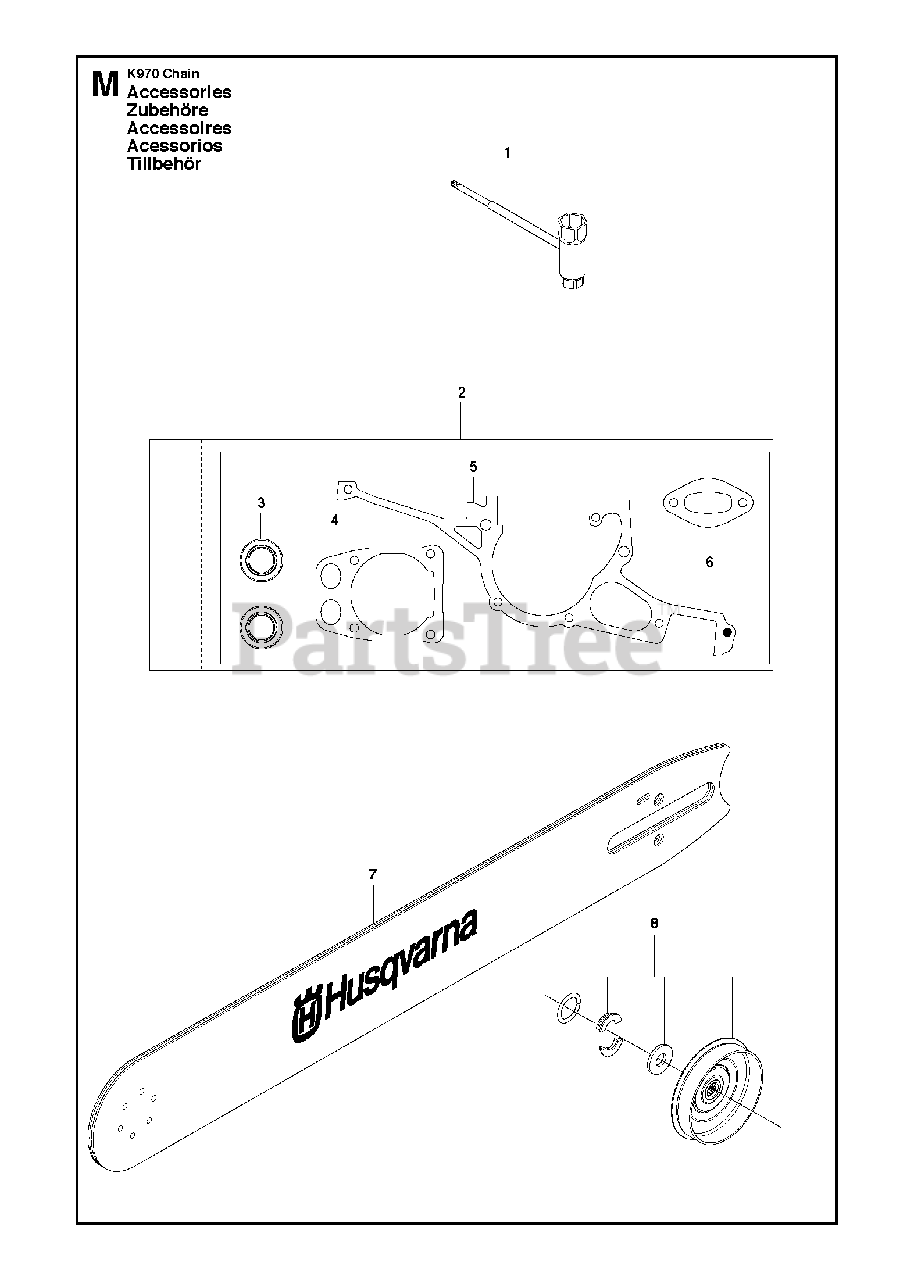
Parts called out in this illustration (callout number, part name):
2	GASKET KITIncl. 3 - 6
3	SEALING RING
6	GASKET
